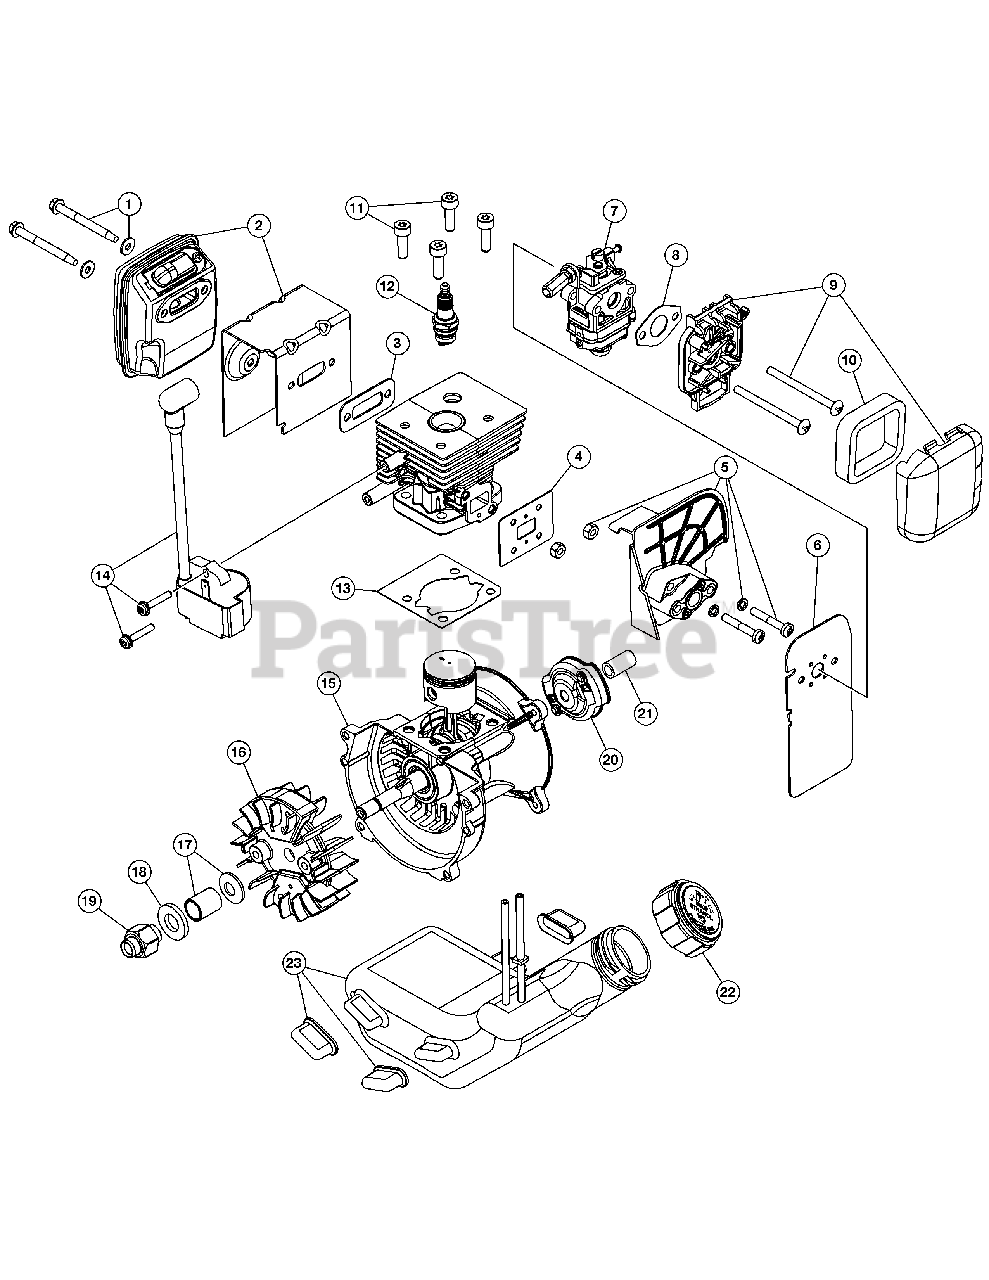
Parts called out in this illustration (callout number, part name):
1	Muffler Screw
2	Muffler Assembly (Incl. 1 & 3)
3	Muffler Gasket
5	Insulator Assembly (Incl. 4)
6	Heat Shield
7	Carburetor
8	Carburetor Gasket
9	Air Cleaner Assembly (Incl. 10)
10	Air Cleaner Filter
12	Spark Plug
13	Cylinder Gasket
14	Ignition Module
15	Shortblock Assembly (Incl. 12 - 14, 16 - 19)
16	Flywheel
18	Washer (qty 2)
19	Flywheel Adapter
20	Pawl Assembly
21	Electric Start Adapter
23	Fuel Tank Assembly (Incl. 22)
